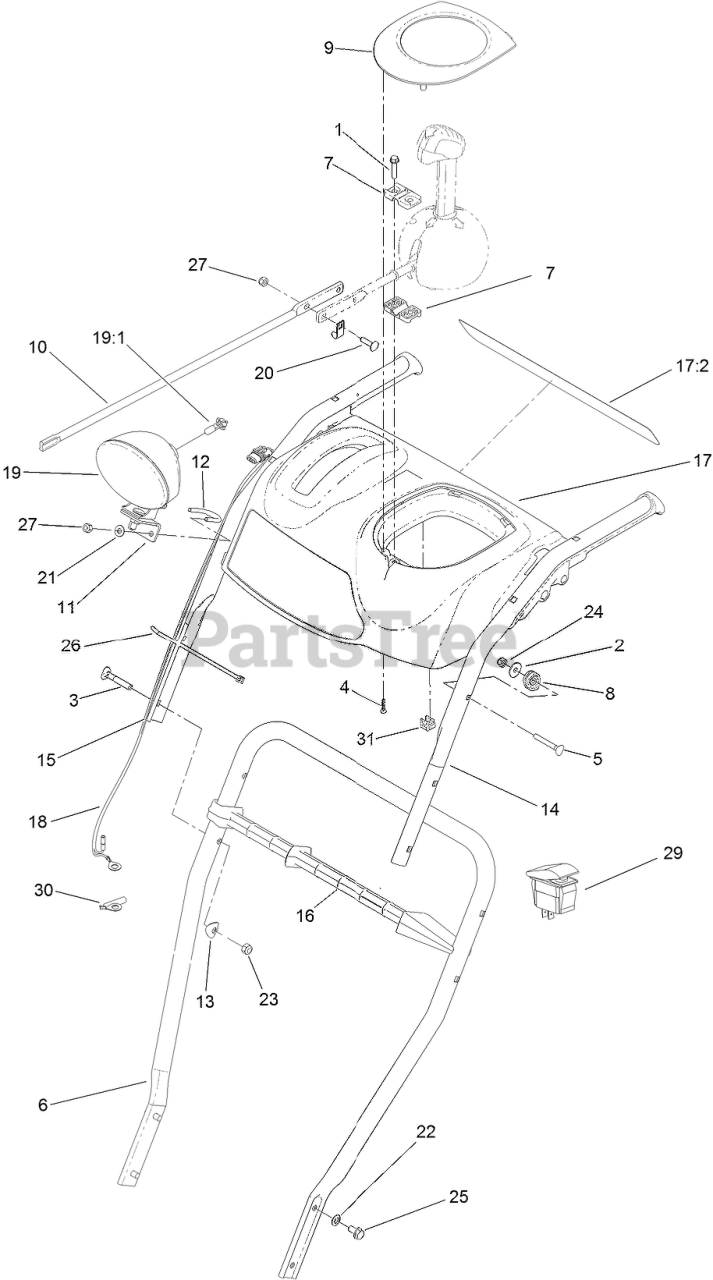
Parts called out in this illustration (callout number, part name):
1	SCREW-PLASTITE
2	WASHER-PLAIN
3	SCREW-HANDLE
4	SCREW-PPH
5	SCREW
6	HANDLE-LOWER
7	SUPPORT-ROD
8	CLAMP-CABLE
9	COVER-PANEL, CONTROL
10	ROD-CHUTE, FRONT
11	BRACKET-LIGHT
12	CLAMP-LIGHT
13	WASHER
14	HANDLE-UPPER, LH
15	HANDLE-UPPER, RH
16	STICK-CLEANOUT
17	CONTROL PANEL ASM
17:2	DECAL-CONTROL
18	HARNESS-WIRE, HEATED GRIPS
19	HEADLAMP ASM
19:1	LAMP-12 VOLT
20	SCREW-CARR
21	WASHER-FLAT
22	WASHER-BELLEVILLE
23	NUT-LOCK, NI
24	NUT-LOCK, NI
25	SCREW-HWHTF
26	TIE-CABLE
27	NUT-LOCK, NI
29	SWITCH-ROCKER, OFF-NONE-ON
30	HARNESS-WIRE, GROUND JUMPER
31	CLIP-EDGE
